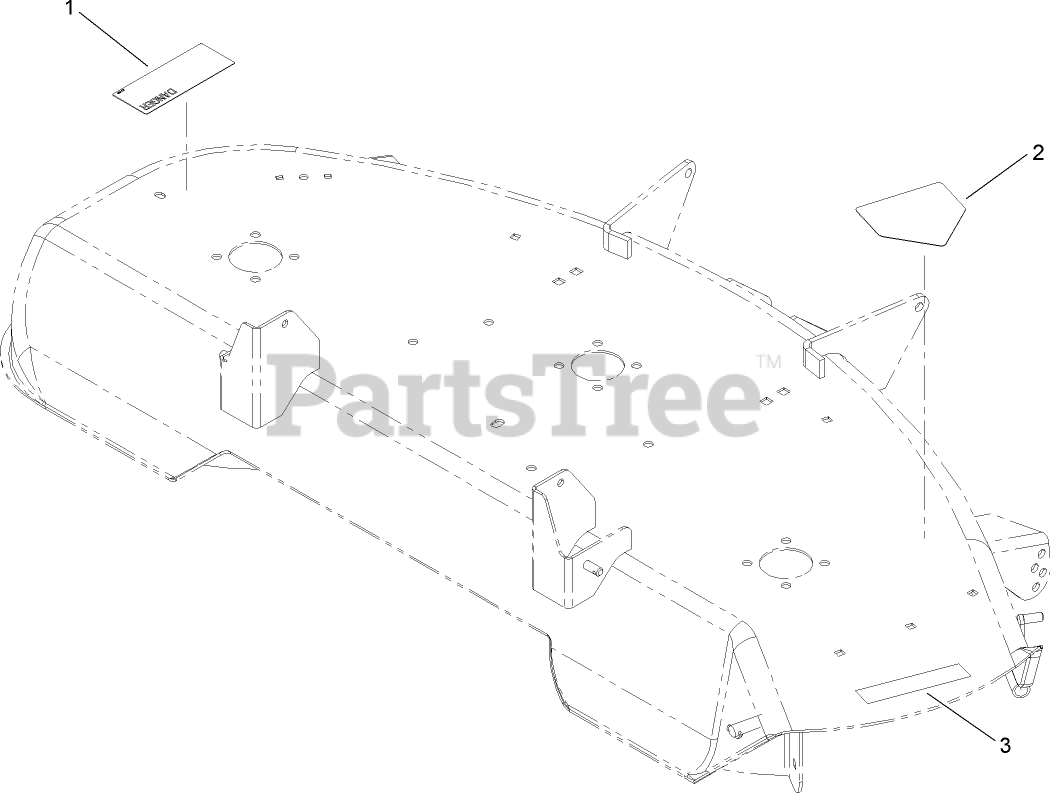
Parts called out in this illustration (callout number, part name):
1	DECAL-DANGER
2	DECAL-DANGER
3	DECAL-DANGER
